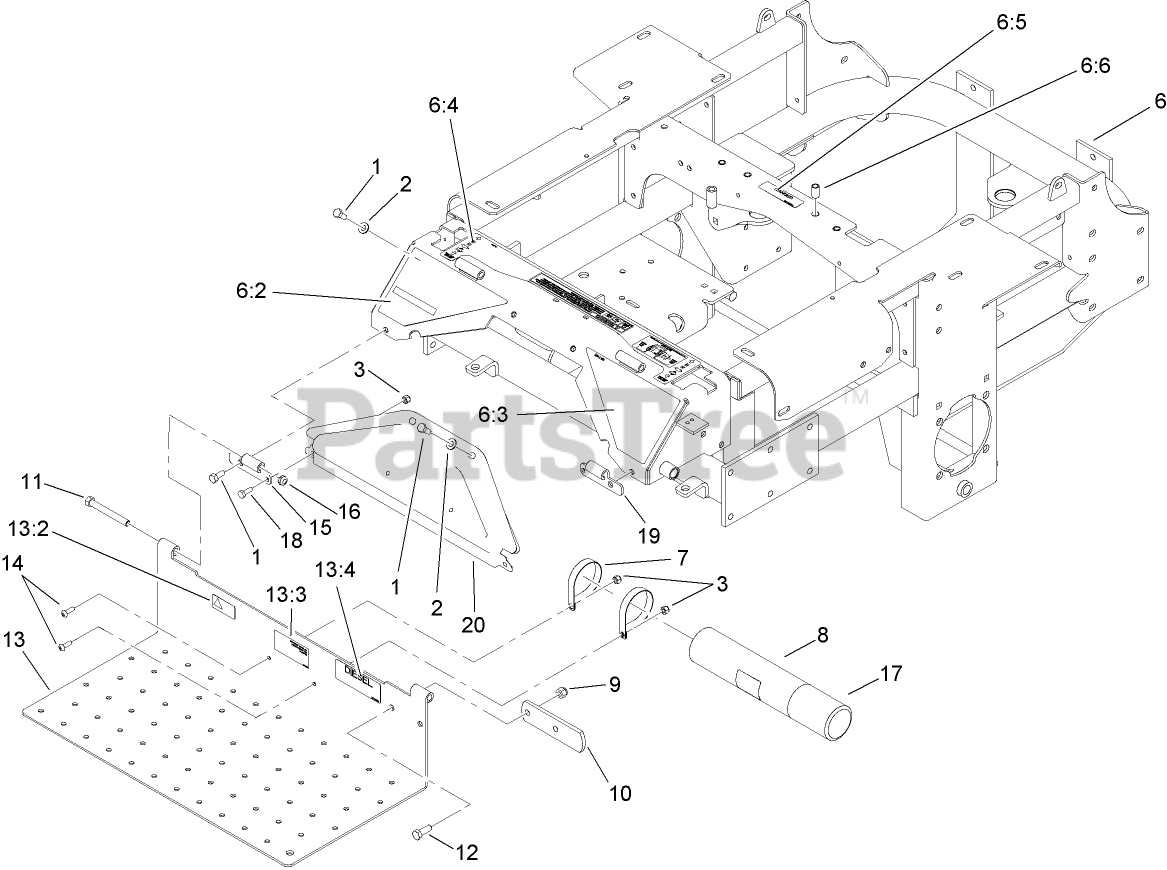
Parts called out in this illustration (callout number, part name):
1	SCREW-HH
2	WASHER-FLAT
3	NUT-LOCK, NI
6	MAIN FRAME ASM
6:2	Decal-Warning
6:3	Decal-Danger
6:4	DECAL-CONSOLE, TOP
6:5	DECAL-COVER, MISSING
6:6	INSERT-THREADED
7	R-Clamp
8	TUBE-MANUAL
9	NUT-LOCK, NI
10	STOP-BRAKE, PARK
11	SCREW-HH
12	SCREW-HH
13	FLOOR PAN ASM
13:2	DECAL-PROTECTION, EAR
13:3	Decal-Location, Manual
13:4	DECAL-DIESEL
14	SCREW-PRH
15	Hinge-Floorpan, LH
16	NUT-LOCK, NI
17	CAP-HOUSING
18	SCREW-HH
19	Hinge-Floorpan, RH
20	Pocket
